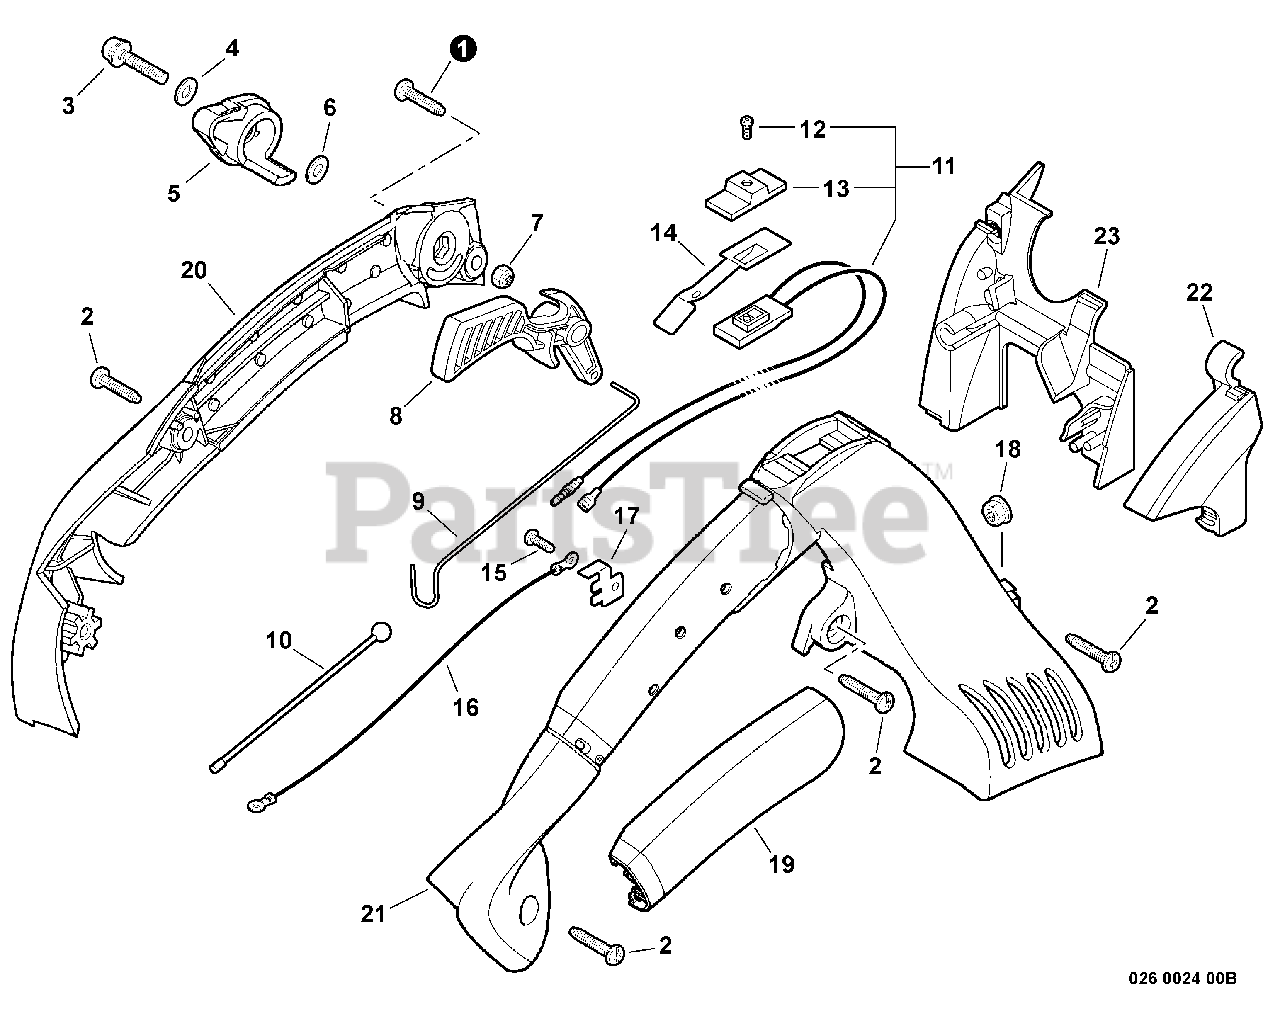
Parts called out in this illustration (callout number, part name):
1	SCREW - 5X20 -- TAPPING
2	SCREW - 5X20 -- TAPPING
3	SCREW - 5X25
4	WASHER - 5
5	LEVER, THROTTLE
6	WASHER - 5
7	LOCKNUT - 5
8	TRIGGER, THROTTLE
9	ROD, THROTTLE
10	CABLE, THROTTLE
11	IGNITION SWITCH ASSY
12	SCREW - 3X10
13	KNOB, SWITCH - ORANGE
14	TERMINAL - GROUND
15	SCREW - 4X10
16	LEAD - GROUND
17	TERMINAL - GROUND
18	NUT - 5 -- FLANGE
19	GRIP, HANDLE
20	HANDLE, CONTROL - LEFT
21	HANDLE, CONTROL - RIGHT
22	COVER, THROTTLE
23	COVER, ENGINE
